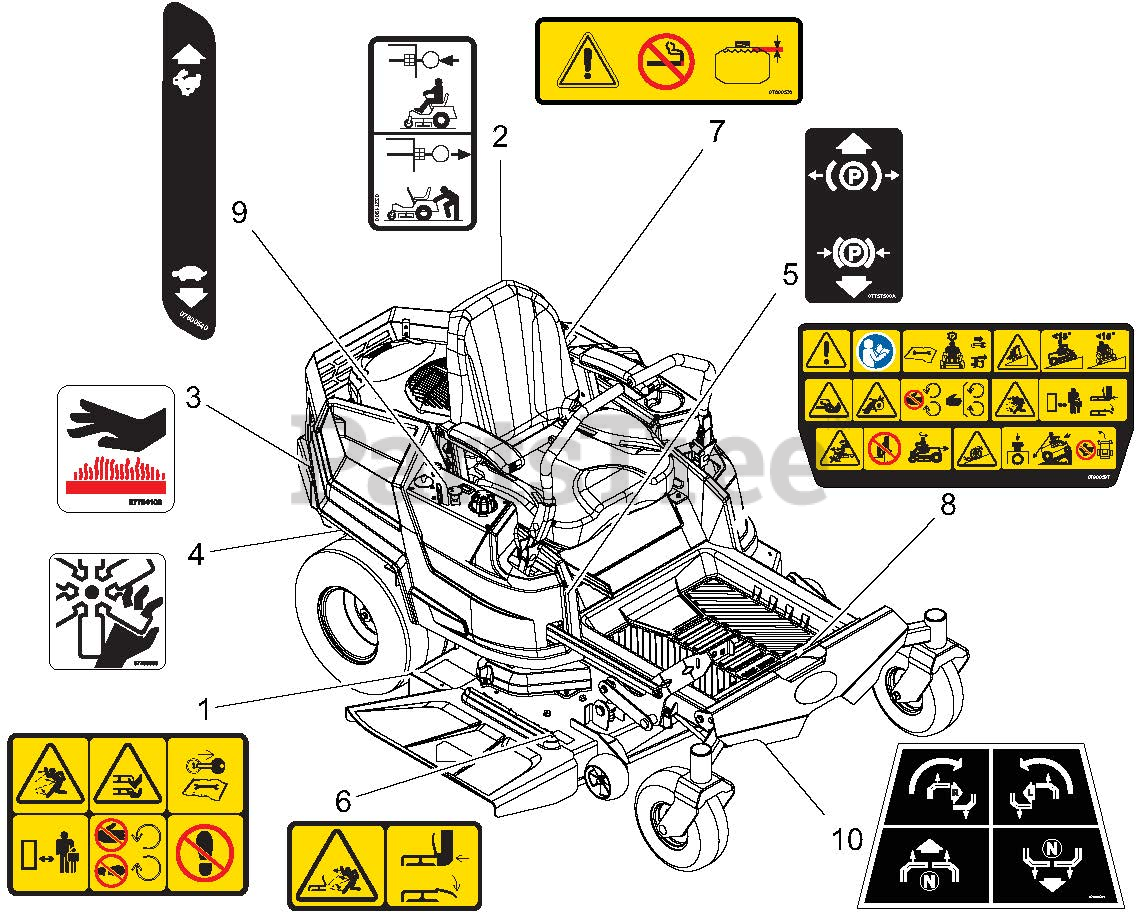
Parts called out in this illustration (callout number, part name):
1	DECAL, SAFETY - MOWER DECK
2	DECAL, TRANSMISSION DISCONNECT
3	DECAL, HOT SURFACE
4	DECAL, DANGER FAN
5	DECAL, PARKING BRAKE LEVER
6	DECAL, SAFETY - DECK GUARDING
7	DECAL-FUEL, WARNING
8	DECAL, MAIN SAFETY
9	DECAL, DASH DECAL
10	DECAL, STEERING
